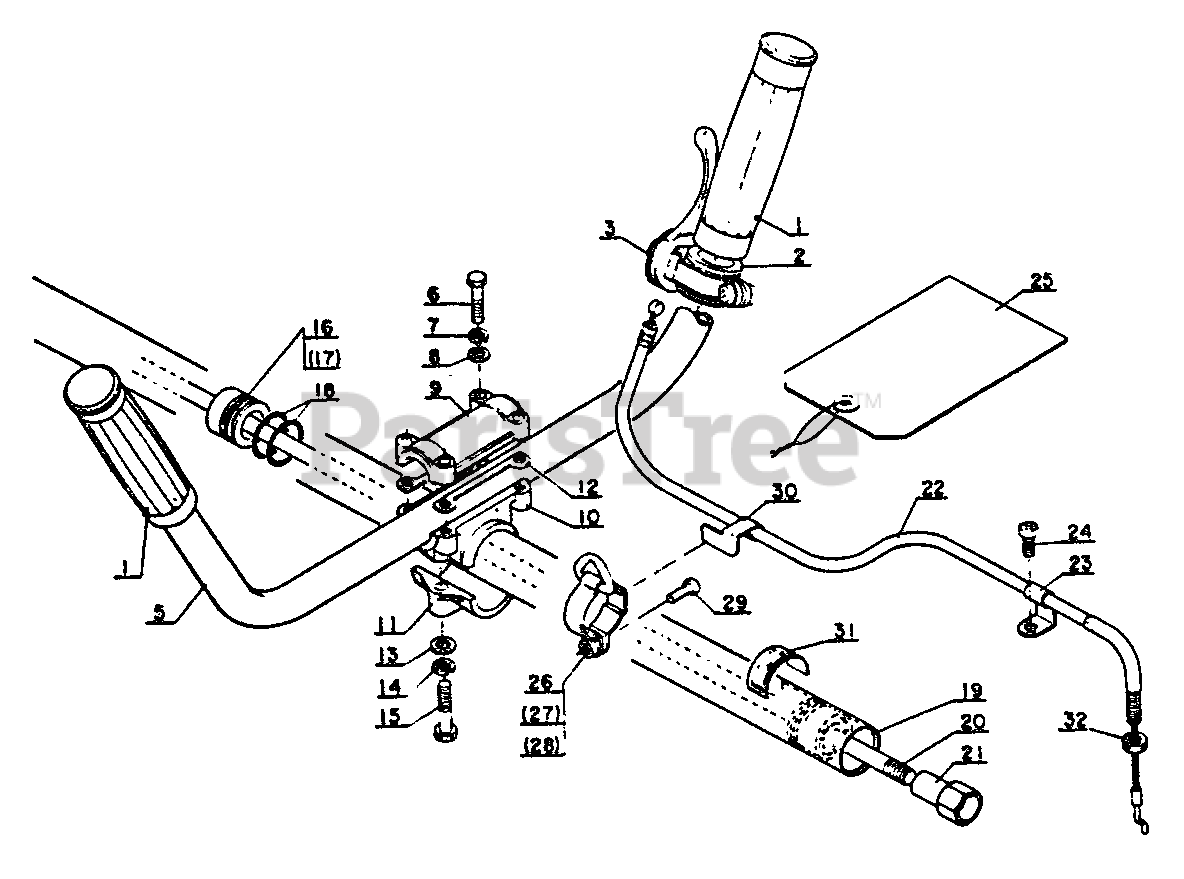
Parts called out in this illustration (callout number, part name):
1	GRIP, HANDLE
3	LEVER, THROTTLE
5	HANDLE
6	BOLT - 5×25
7	WASHER, SPRING 5
8	WASHER, FLAT 5.5×10×0.8
9	BRACKET ASSY, HANDLE
10	BRACKET ASSY, HANDLE
11	BRACKET ASSY, HANDLE
13	WASHER 6.5×11.5×0.8
14	WASHER, SPRING 6
15	BOLT - 6×30
16	STOPPER
18	O-RING - 22
19	PIPE, MAIN
20	DRIVESHAFT
22	CABLE, THROTTLE
23	CLAMP
24	SCREW - 5×8
31	LABEL - CAUTION
